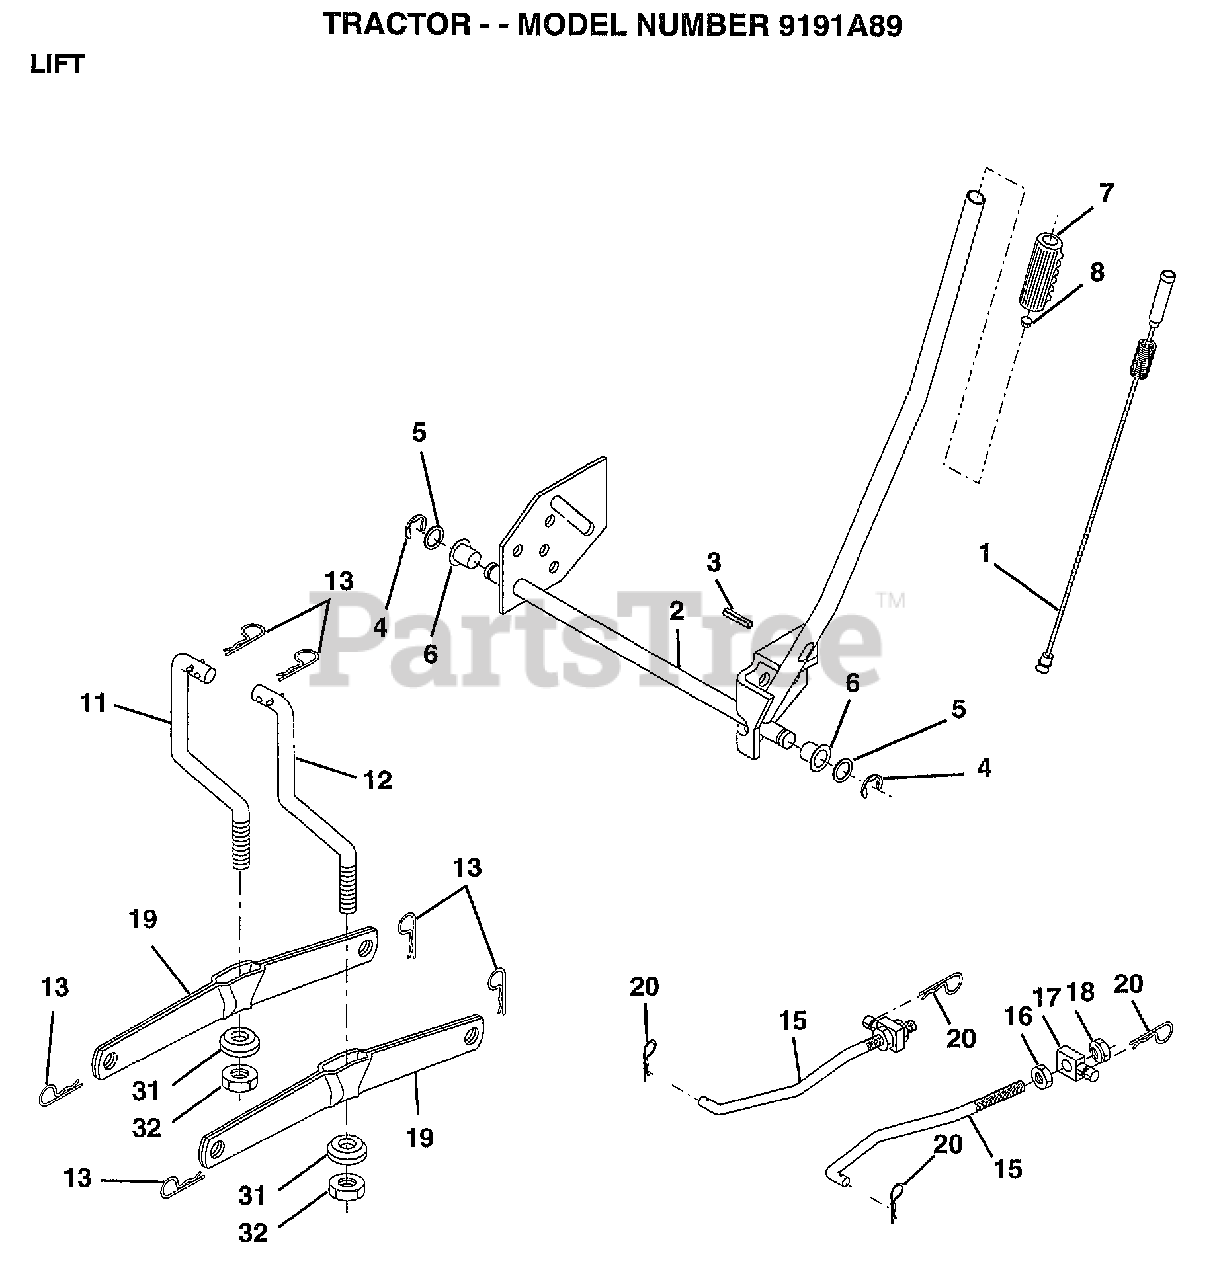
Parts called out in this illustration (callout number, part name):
1	WIRE ASM W.SPRING
2	"SHAFT ASM LIFT,RH"
3	PIN-GROOVE LT
5	WASHER
6	NYLON BEARING
7	GRIP
15	LINK.FRONT
16	NUT
17	TRUNION
18	NUT.LK.W/WSH.1/2.
19	ARM SUSP REAR
20	RETAINER.SPRING
31	BEARING PVT LH
32	NUT.CROWNLOCK.3/8
